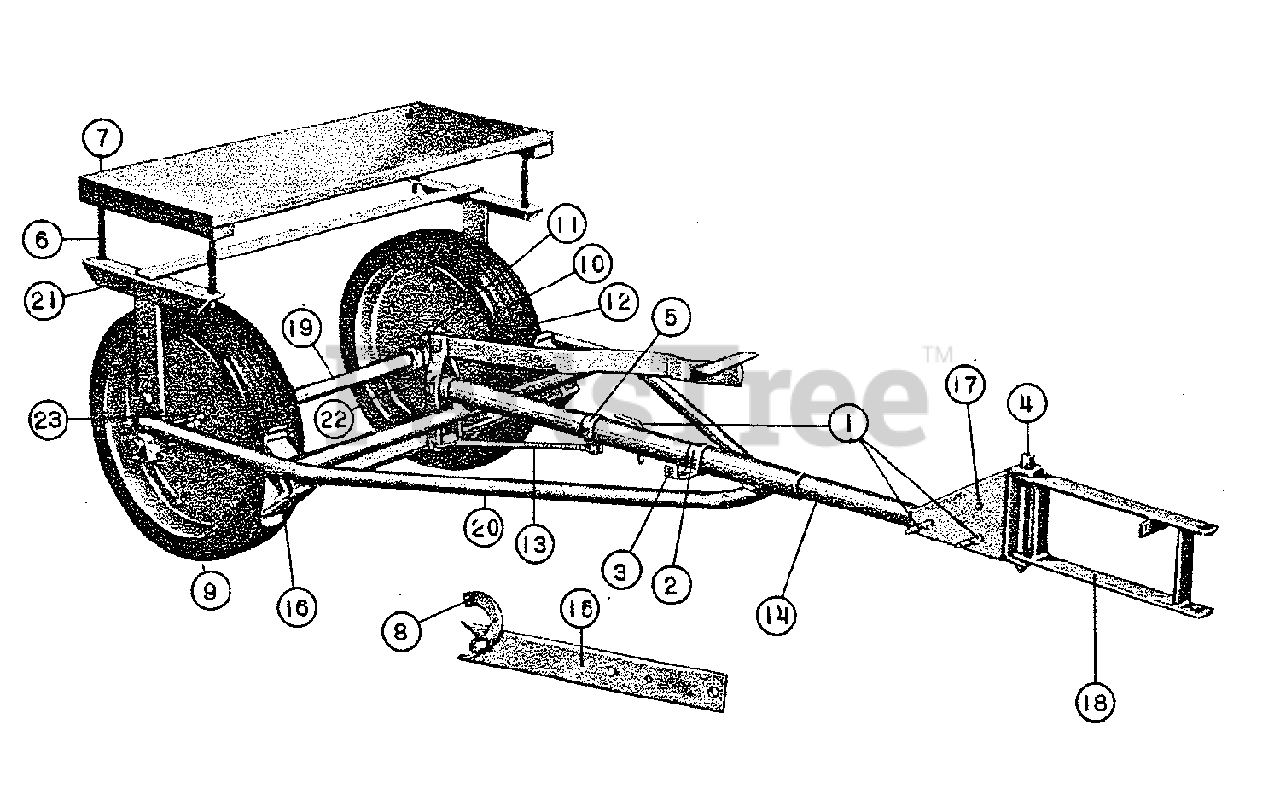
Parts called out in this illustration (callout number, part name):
1	PIN, Tongue
3	BRAKE, Lock
4	PIN, King
5	CLAMP, Spring
6	SPRING, Seat
7	STUD, Seat
9	BUSHING, For Wheel
10	DISC, Wheel
11	HUB, For Wheel
13	SPRING, Brake
15	BODY PROP
16	SHOE, Brake
17	CLEVIS ASSEMBLY
18	TONGUE EXTENSION
20	FRAME, Cart
21	FRAME, Dump
22	BRAKE ASSEMBLY
